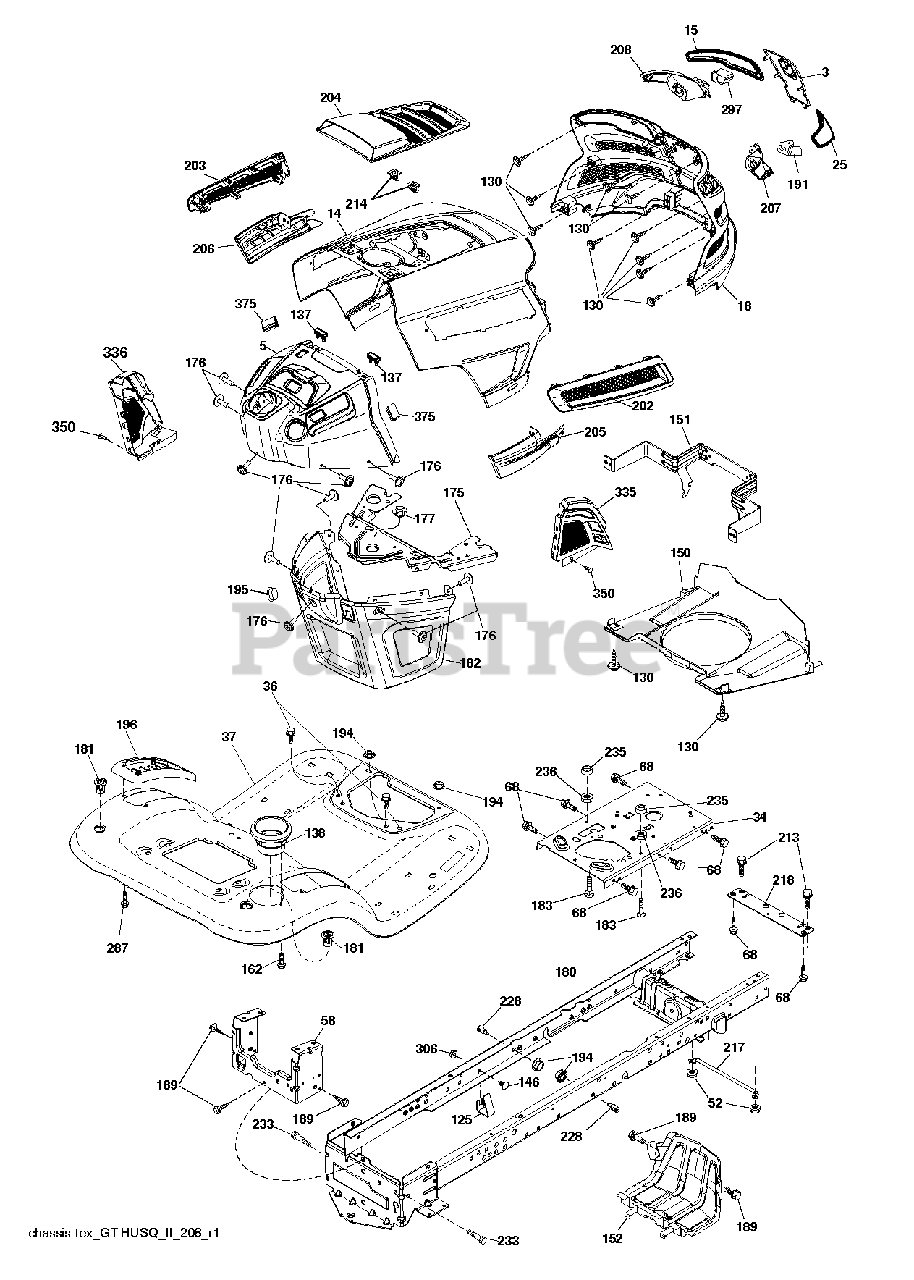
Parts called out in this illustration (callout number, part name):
3	APPLIQUE.SUBASM.GT.HUSQ.II
5	UPPER.GT2.SVC.MINDING.C-O.M;H
14	HOOD.ASM.HUSQVARNA.GT.TEX.ORAN
15	LENS.HEADLIGHT.LH.GTII.2011
18	GRILLE.SUBSTRATE.2011.
25	LENS.HEADLIGHT.RH.GTII.2011
34	PLATE.ENGINE.WELDED.CHASSIS
36	SCREW 5/16"
37	FENDER.TLT.PDL.CNTRL.W/CPH.ORG
52	LOCKNUT
58	DRAWBAR UPPER 2PC SMALL FENDER
68	SCR 5/16-18 X 1/2 SELFTAP ZN
125	CLIP.FUEL.LINE
130	SCREW.#10 X 0.750.BOS
137	BUMPER DASH
138	HOLDER.CUP.LT.GREY
146	BOLT.RDHD.SHT.SQNK.3/8-16X5/8
150	AIR.DUCT.GTV.BLACK
151	BRACKET.PIVOT.HOOD.GT.HUSQ.II
152	SHIELD.BROWNING.PNT.GT.V2
162	SCREW.HI-LO.CONSOLE
175	Crossmember Plate
176	SCREW.#10-24X5/8.RN.QU
177	BUSHING STEERING
180	CHASS.WLDMNT.TL.12GA/2P.48/54
181	BUSHING.MNT.FEND.CRGO.TEX.49
182	DASH.LOWER.COMMON.12V.ADAPTOR
183	BOLT.5/16-18X1-1/4 FULL THD
189	SCREW, 3/8-16X3/4
191	INSERT.REFLECTIVE.RH.HUSQ.GTII
194	NUT LOCK HEX FLANGE 5/16-18
195	PLUG.HOLE.DASH.LOWER.12V.BLK
196	DECKLFT.CONSOL FULL ASSM GREY
202	VENT.SIDE.RH.GT.HUSQ.II.
203	VENT.SIDE.LH.GT.HUSQ.II.498
204	VENT.TOP.HUSQ.GT2
205	SIDE.TRIM.RH.GT.HUSQ.II
206	SIDE.TRIM.LH.GT.HUSQ.II.GRAY
207	BEZEL LIGHT.RH.GT.II.MYLAR
208	BEZEL LIGHT.LH.GT.II.MYLAR
213	BOLT
214	CLIP.RETAINER.TINNER.
217	ROD.PIVOT.HOOD
218	X-PIECE.HOOD.STOP.NON/
228	STUD.FASTNER.W/ANTI-ROTATE
233	BOLT.SHOULDER
235	SPACER FENDER
236	NUT.CENTERLOCK.5/16-
287	SCREW 1/4X20
297	INSERT.REFLECTIVE.LH.HUSQ.GTII
306	NUT LOCK FLG 3/8-16 UNC
335	COVER.LOWER.DASH.RH.BLACK
336	COVER-LH.LOWER.DASH.GT2.BLACK
350	CLIP.X-MAS.TREE
375	BUMPER CLIP-ON. DASH 1"
